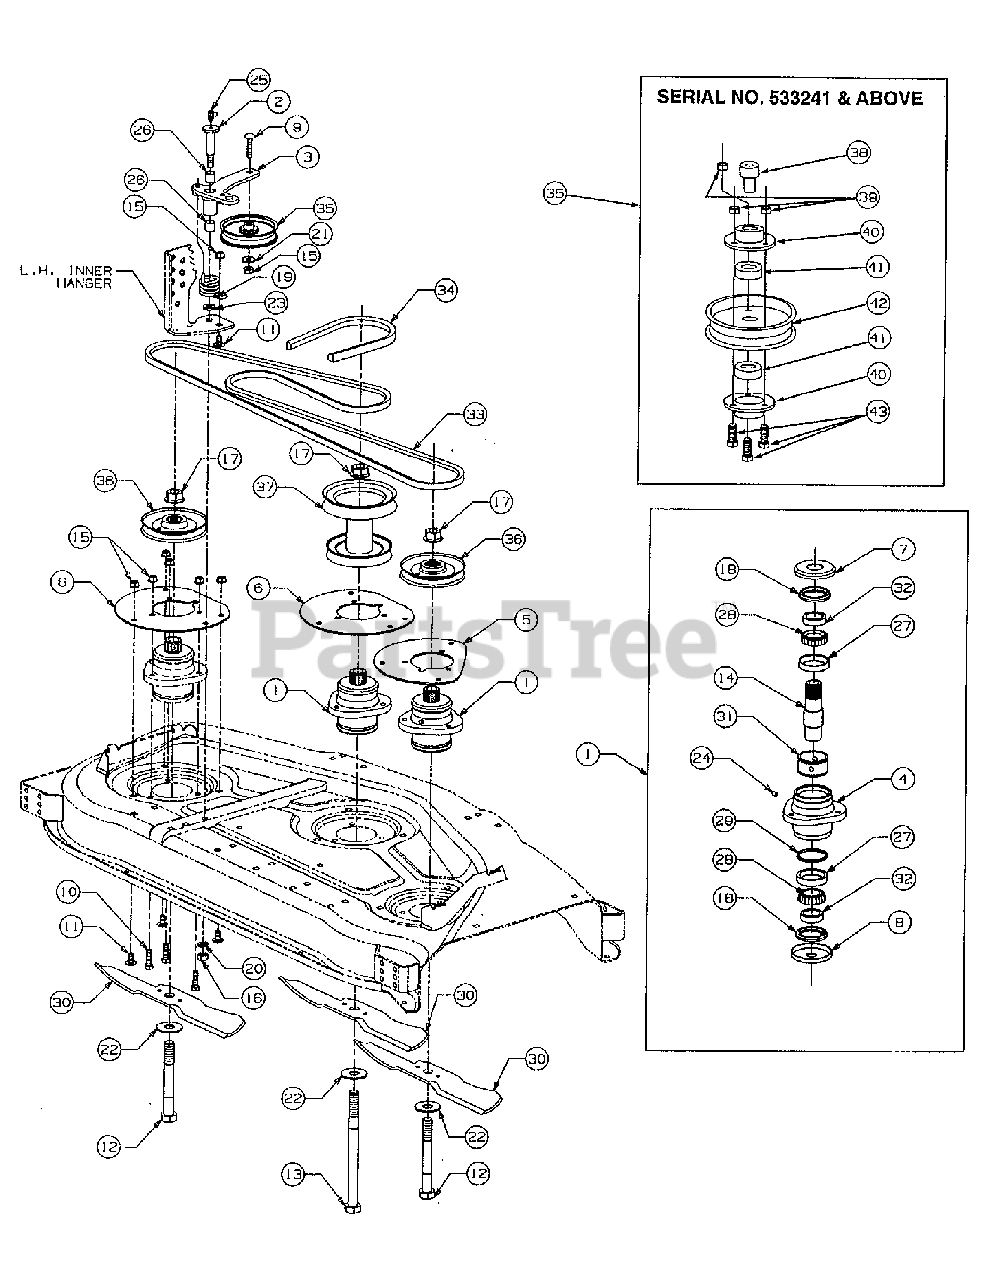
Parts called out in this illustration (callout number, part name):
1	Spindle Assembly, Complete
2	Bolt, Shoulder
7	Cup, Top Spindle
9	Bolt, Carriage, 3/8-16 x 1.75
10	Screw, Hex Cap, 3/8-16 x 1.25 Gr 5
11	Bolt, Sht Nk Carriage 3/8-16 x .75 Gr 5
12	Bolt, Hex Hd Blade, 3/4-16 x 6.0
13	Bolt, Hex Hd Blade, 3/4-16 x 9.5
14	Shaft, Blade Spindle
15	Nut, Hex Flanged Lock, 3/8-16
16	Nut, Hex, 7/16-14 Gr 5
17	Nut, Hex Flange 3/4-16
18	Seal, Oil
19	Spring, Torsion
20	Washer, Lock 7/16
21	Washer, Special, .378 x 1.0 x .125 Thk
22	Washer, Flat .781 x 2.0 x .105 Thk
23	Washer, Flat .469 x .875 x .105
24	Fitting, Lube
25	Fitting, Lube 90Deg 1/4-28 Tapper Thd
26	Bearing, Sleeve
27	Cup, Bearing
28	Cone, Bearing
29	Spacer, Bearing
30	Blade, Mower 16.5
30	Blade, Mower Hard Coated, 16.5
30	Blade, Mower Hi-Lift, 16.5
31	Spacer, Bearing Cup
32	Ring, Seal
33	Belt, Spindle A-Sect x 107.3
34	Belt, PTO B-Sect x 62.04
35	Pulley, Flat Idler
35	Pulley Assembly, Idler
36	V-Pulley 4.65 OD
37	Pulley, Deck, 5.07 OD & 5.75 OD
38	Spacer, Shoulder
39	Nut, Hx Insrt Lock, 1/4-20
40	Cup, Bearing
41	Bearing, Call
42	Pulley, Flat Idler
43	Screw, Hex Cap, 1/4-20 x .62 Gr 5
